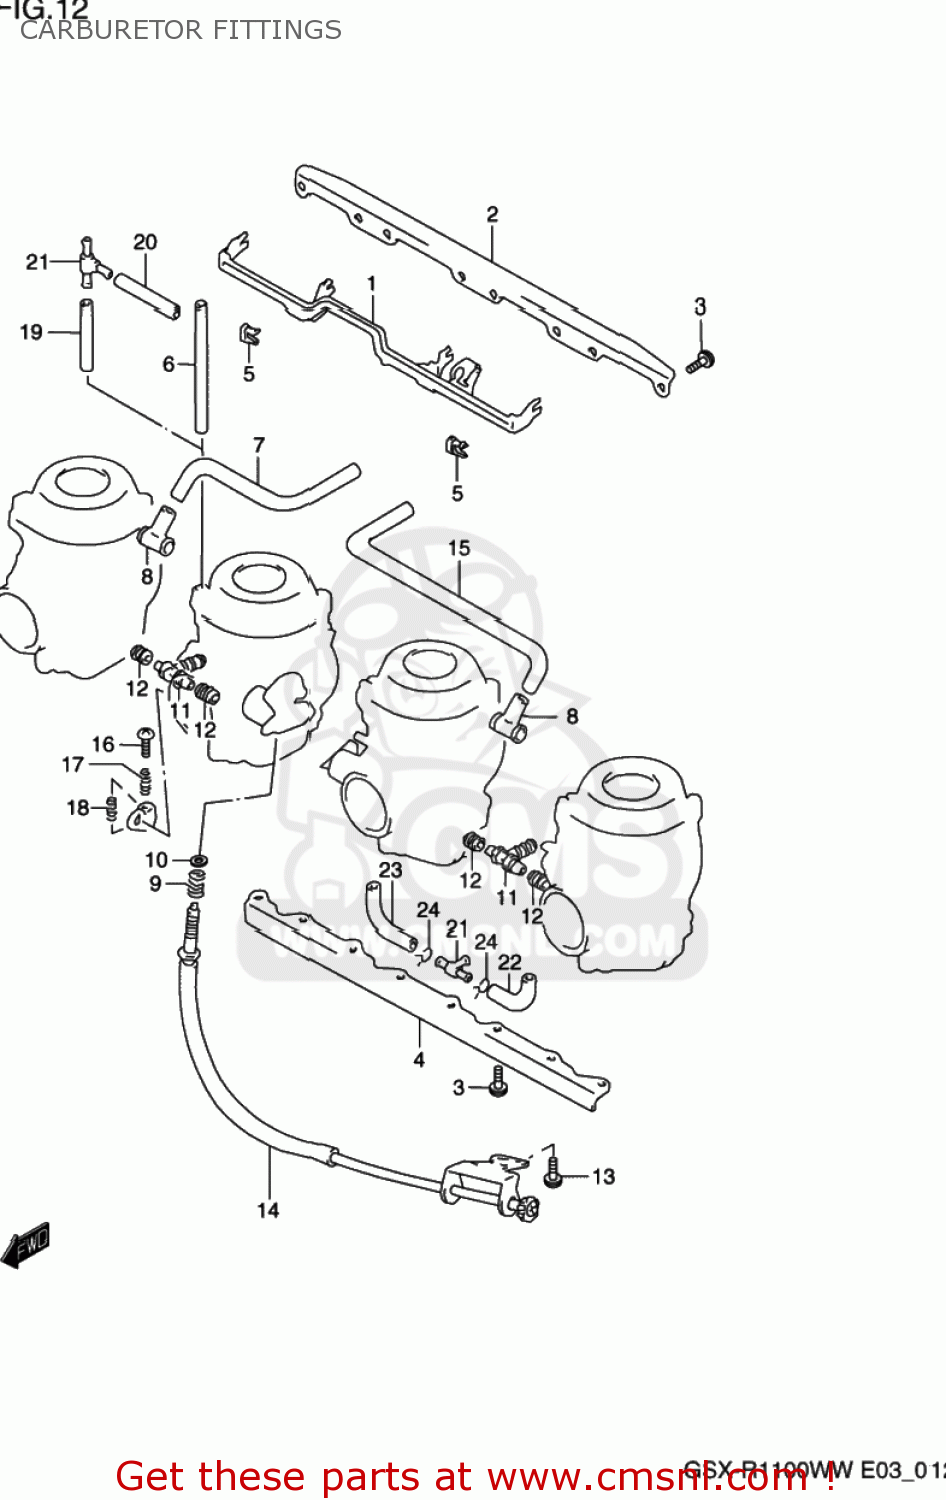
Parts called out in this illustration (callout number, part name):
1	LEVER,STARTER
2	PLATE
3	SCREW
4	PLATE
5	HOLDER
6	HOSE
7	HOSE
8	HOSE
9	SPRING
10	WASHER
11	NIPPLE
12	SEAL
13	SCREW
14	ADJUSTER ASSY
15	HOSE
16	SCREW
17	SPRING
18	SPRING
19	HOSE(5X9X600)
20	HOSE(5X9X600)
21	NIPPLE
22	HOSE
23	HOSE
24	CLIP
